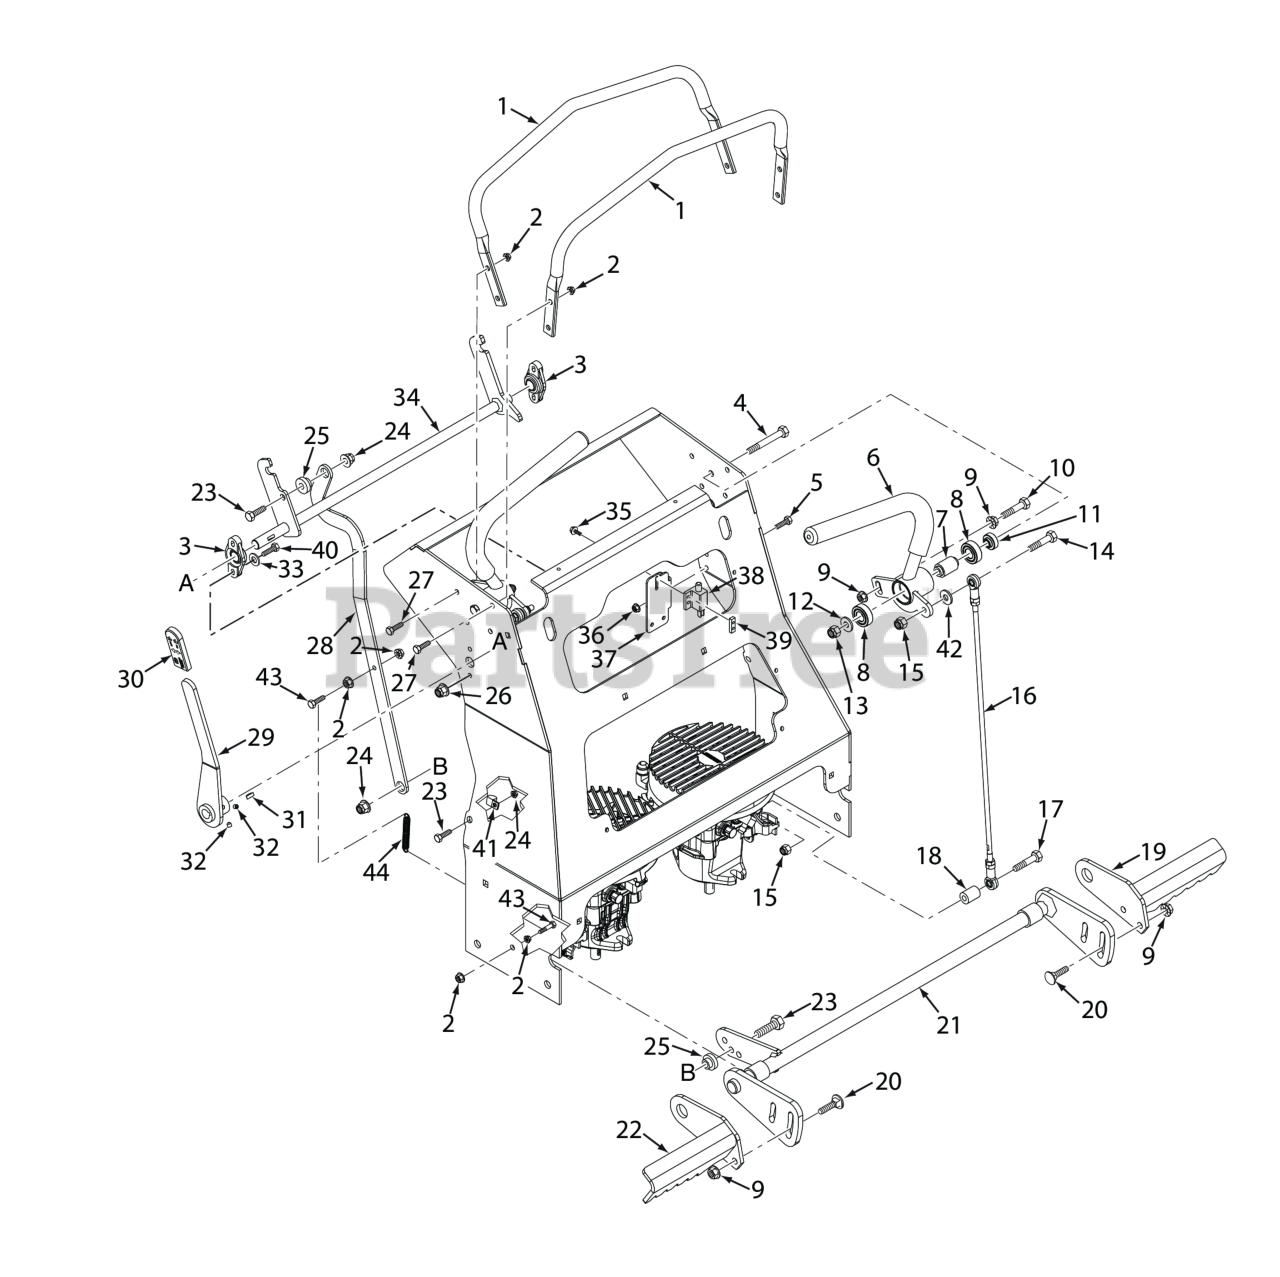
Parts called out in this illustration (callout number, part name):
1	Reference Bar
2	Nut, Serrated Flange 5/16-18 (Right Front Engine Mounting, Briggs and Kohler Only)
3	Bearing
4	Capscrew, Hex Head 3/8-16 x 3.25"
5	BOLT, HEX HEAD, 1/4-20 X 3/4 GR.5
6	Handlebar Assy., LH
7	Spacer, Bearing
8	BEARINGS, BALL, NEUTRAL RETURN
9	NUT, 3/8-16 SERRATED FLANGE HEX HEAD
10	Capscrew, Hex Head 3/8-16 x 2.0"
11	Spacer, Controls
12	Flatwasher, 3/8 (.391 x .938 x .105 HD) Grade 8
13	HEX NUT, ELASTIC STOP LOCK, 3/8-16
14	Bolt, 5/16 - 18 x 1 - 1/4" Hex Head
15	HEX NUT, ELASTIC STOP LOCK, 5/16-18
16	Linkage Assy., Steering
17	Bolt, Hex Head 5/16-18 x 2-1/2" (x3) (35BV & 37BV-EFI)
18	Spacer (excludes SVRII-36A)
19	Brake Paddle Weldment, RH
20	Carriage Bolt, 3/8-16 x 1.0"
21	Bellcrank Weldment, Brake
22	BRAKE PADDLE WLMT, LH
23	Bolt, Hex Head 3/8-16 x 1-1/4", Kawasaki FX / FT & FT-EFI
24	Nut, Flange Elastic Stop Nut, 3/8-16
25	BUSHING, BRONZE - .376 ID X .627 OD
26	Nut, Flanged Elastic Stop 1/4-20
27	BOLT, SERRATED FLANGE HEX HEAD 5/16-18 X 3/4"
28	Link, Brake Engage
29	Lever Assembly, Brake, SVRII
30	Grip, Brake Handle
31	KEY, 3/16 X 3/16 X 1-1/2
32	Set Screw 1/4-20 x 1/4"
33	Flatwasher, 1/4 (.281 x .625 x .065)
34	Lock Weldment, Neutral
35	Screw, Hex-Slotted Washer Head #10 32 x 3/4"
36	NUT, 1/4-20 SERRATED FLANGE HEX HEAD
37	Bracket, Neutral Switch
38	Switch, Interlock, Park Brake Normally Open
39	Plate, Threaded
40	Capscrew, Hex Head 1/4-20 x 1"
41	CLAMP, CABLE - 1.00
42	Flatwasher, 5/16-.344 x .688 x .065 (48V / 52V)
43	Bolt, Hex Head 5/16-18 x 1-1/2" (Right Front Engine Mounting, Briggs and Kohler Only)
44	Spring, Deck Lift
